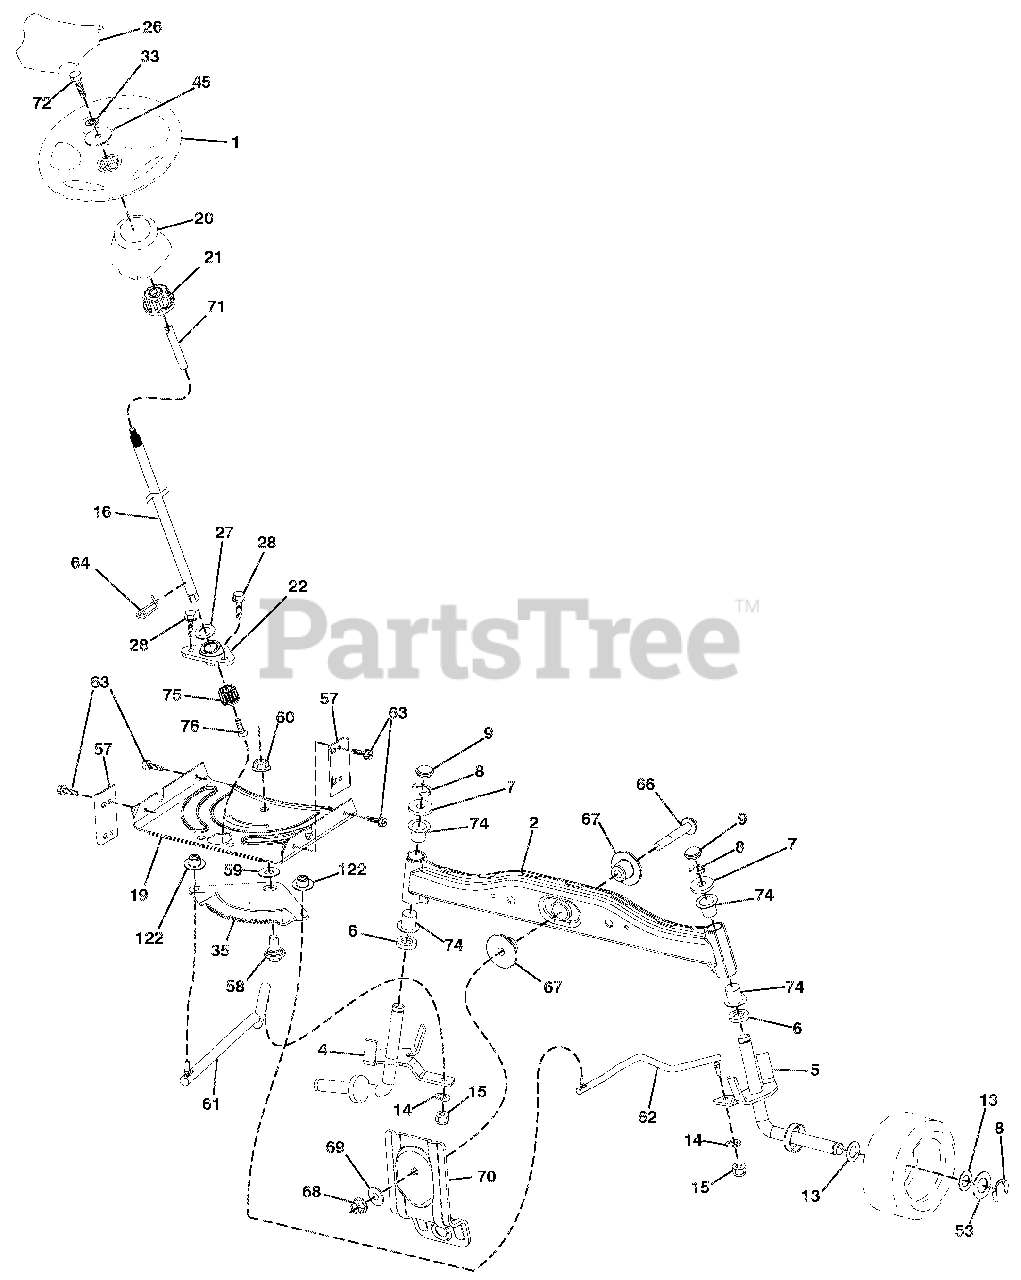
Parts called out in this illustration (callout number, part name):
1	WHEEL.STEERING.HARD RIM.BLACK
2	AXLE ASM.WELDED
4	SPINDLE.WELDED.LH.15"TEX
5	SPINDLE.WELDED.RH.15"TEX
6	WAHSER THRUST .75 X 1.230
7	WASHER.25/32 X 1-5/8 X 16GA.
8	RING.KLIP.#T5304-75
9	CAP.SPINDLE.FR.TOP.BLK.
13	WASHER.25/32 X 1 1/4 X 16 GA.
14	Washer, Lock 3/8
15	NUT.CROWNLOCK.3/8-24
16	STEERING SHAFT
19	PLATE.STEER.DDL.NLT/NGT
20	BOOT.STEERING
21	ADAPTER.WHEEL.STRG..760
22	STEER.SUPT. LOWER
26	CAP WHEEL STEERING HRS/SRS BLK
27	Washer 21/32 x 1 x 16 Ga.
28	SCREW.HEXWSH THDR3/8-16X3/4.BL
33	Washer, Lock 5/16
35	GEAR SECTOR.PLATE.DDL.NLT/NGT
45	WASHER.11/32ID X2 3/8OD X 12GA
53	WASHER.HARDEN..793 X 1.637X060
57	BRACKET.UPSTOP.TEX
58	BOLT.SHOULDER.SECTOR.PIVOT.CFM
59	WASHER.THRUST.SECTOR.STEER.NLT
60	NUT.FLANGE LOCK.5/8-11
61	DRAGLINK.LH.BALLSTUD.DDL.
62	DRAGLINK.RH.BALLSTUD.DDL
63	SCREW.5/16-18X3/4.SMGML.TAP/BL
64	RETAINER.CLIP.SPRING.STEERING
66	BOLT.HEX.FGHD.7/16-14 X 3.SERR
67	BUSHING.PM.FRONT AXLE
68	NUT.LOCK.FLANGE.7/16-14.GR5
69	WASHER.1.5 X .505 X .118
70	BRACKET
71	Extension Steering
72	Bolt 5/16-18 x 14 w/Patch
74	BEARING COL STRNG BLK
75	PINION
122	CAP GEAR SECTOR
